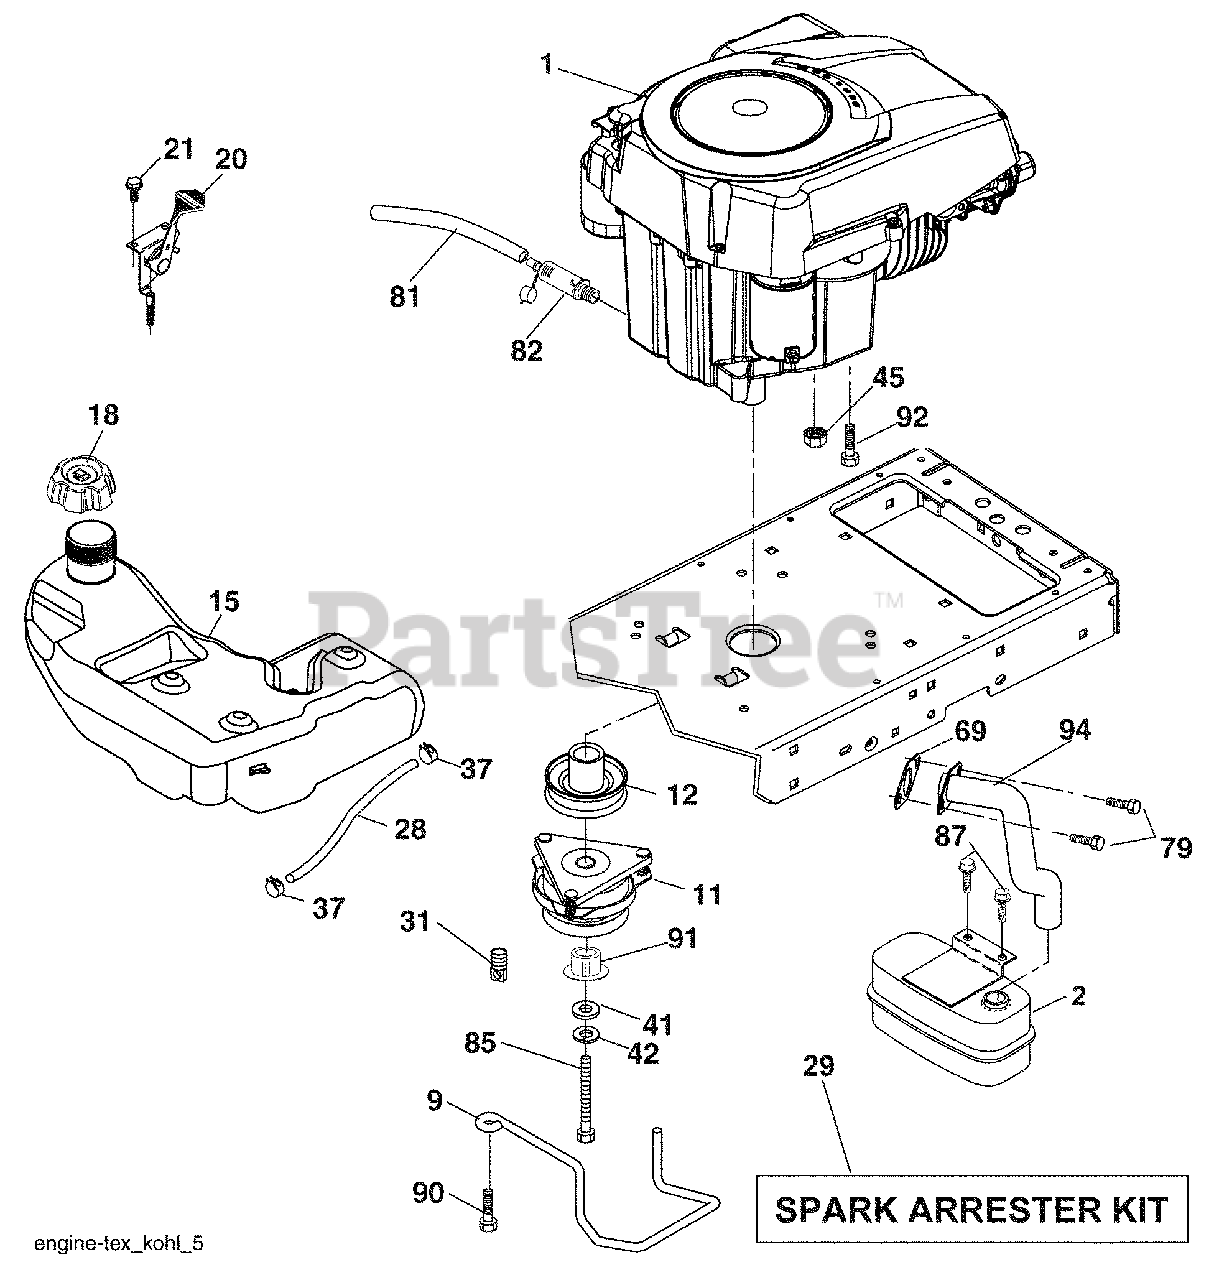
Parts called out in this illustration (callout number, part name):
9	Keeper Belt Engine
11	Clutch
12	Pulley Engine
15	Tank Fuel
18	Cap Asm
20	Control Throttle
21	Screw 1/4 - 20 x 1/2
28	Fuel Line
29	Spark Arrester Kit
31	Clip Push-in Hinged
37	Clamp Hose
41	Washer 1-1/2 OD x 15/32 ID x .250
42	Washer Lock 7/16
45	Nut Keps Hex 1/4-20 unc
79	Screw Socket HD 5/16-18 x .75
81	Tube Drain Oil Easy
82	Plug Drain Oil
85	Bolt Hex 7/16-20 x 4 x Gr. 5-1.5 Thr
87	Bolt 5/16-18 UNC x 3/4 w/Sems
90	Screw 3/8-16 x 1
91	Bushing 1.375 OD
92	Screw 3/8-16 x 1
94	Tube Exhaust
